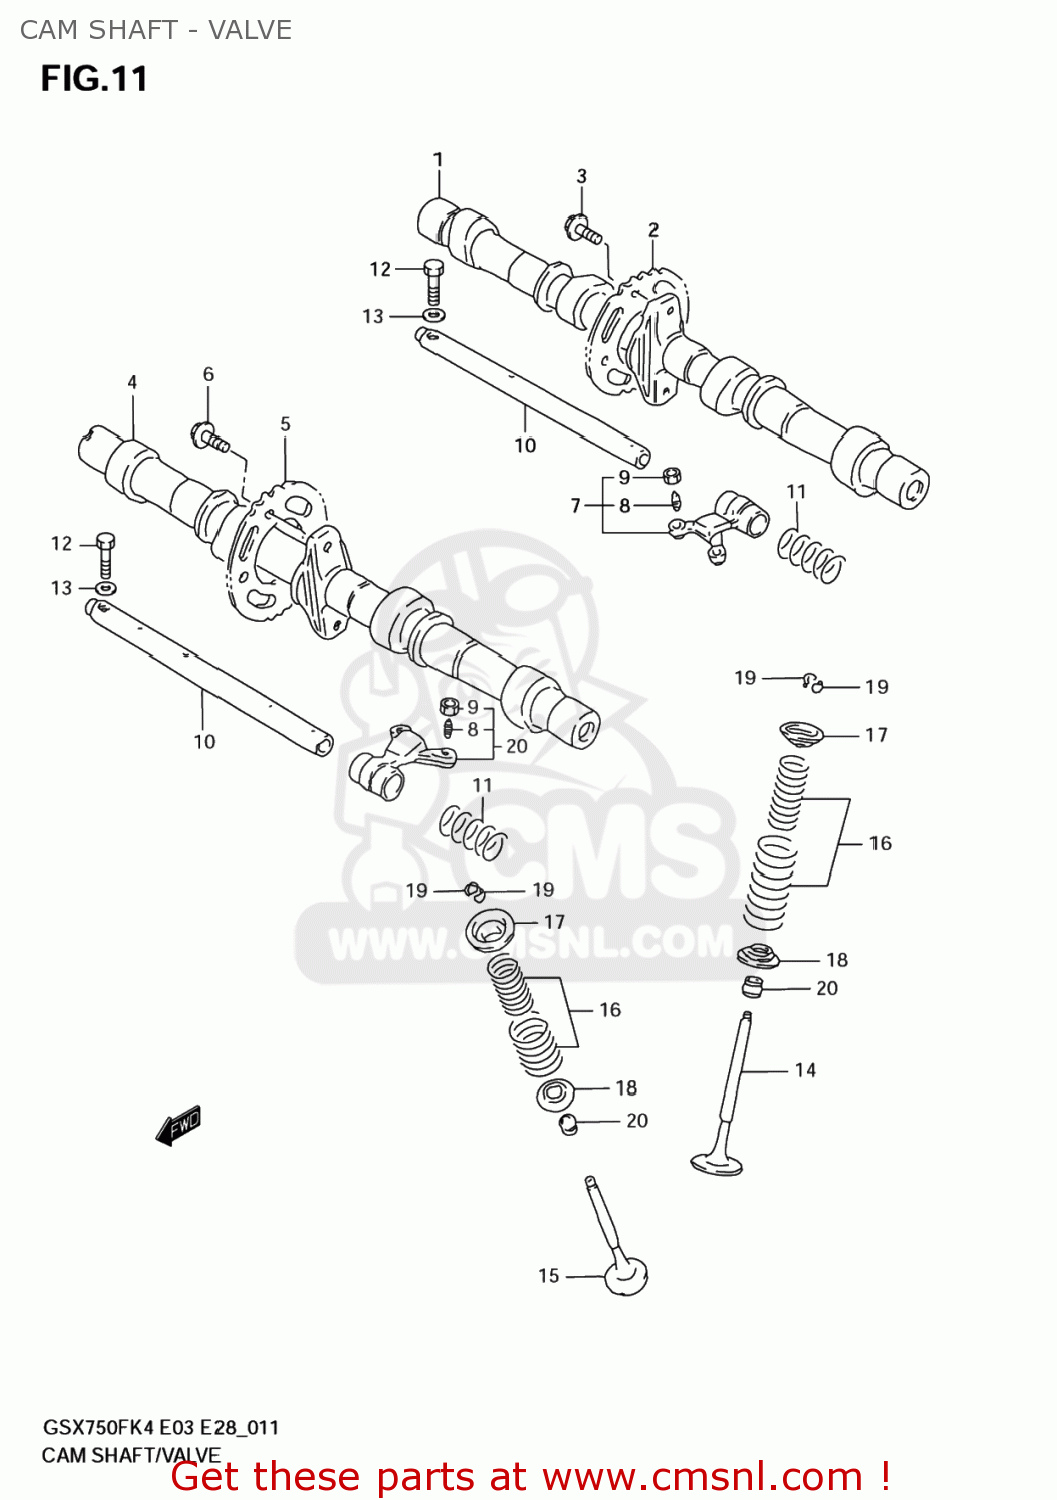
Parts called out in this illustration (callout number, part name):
1	CAMSHAFT,INTAKE
2	SPROCKET,CAMSHAFT
3	BOLT(7X11)
4	CAMSHAFT,EXHAUST
5	SPROCKET,CAMSHAFT
6	BOLT(7X11)
7	ARM,VALVE ROCKER
8	SCREW,TAPPET ADJUSTING
9	NUT,TAPPET ADJUSTING
10	SHAFT,VALVE ROCKER ARM
11	SPRING
12	BOLT(6X30)
13	WASHER
14	VALVE,INTAKE
15	VALVE,EXHAUST
16	SPRING SET,VALVE
17	RETAINER,VALVE SPRING
18	SEAT,VALVE SPRING
19	COTTER VALVE
20	SEAL,OIL(5X10X9.7)
